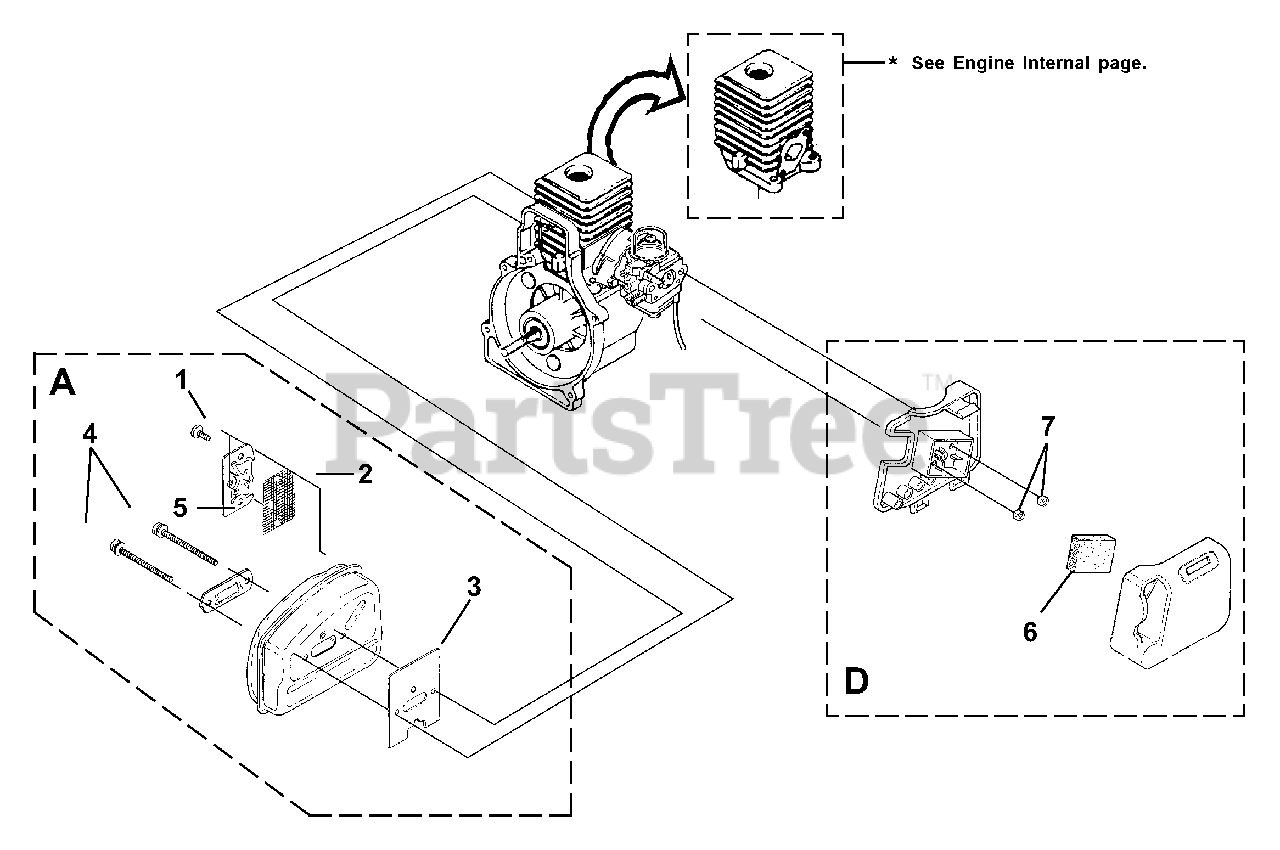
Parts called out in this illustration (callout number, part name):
1	SCREW, Taptite- (8-32 X 3/8")
2	SCREEN-Spark
3	GASKET-Muffler
4	SCREW, Truss Hd. - (10-24 X 2")
5	DEFLECTOR-Muffler
6	FILTER-AIR
7	NUT-Hex (10-24)
A	MUFFLER ASSY.
D	AIR FILTER KIT
